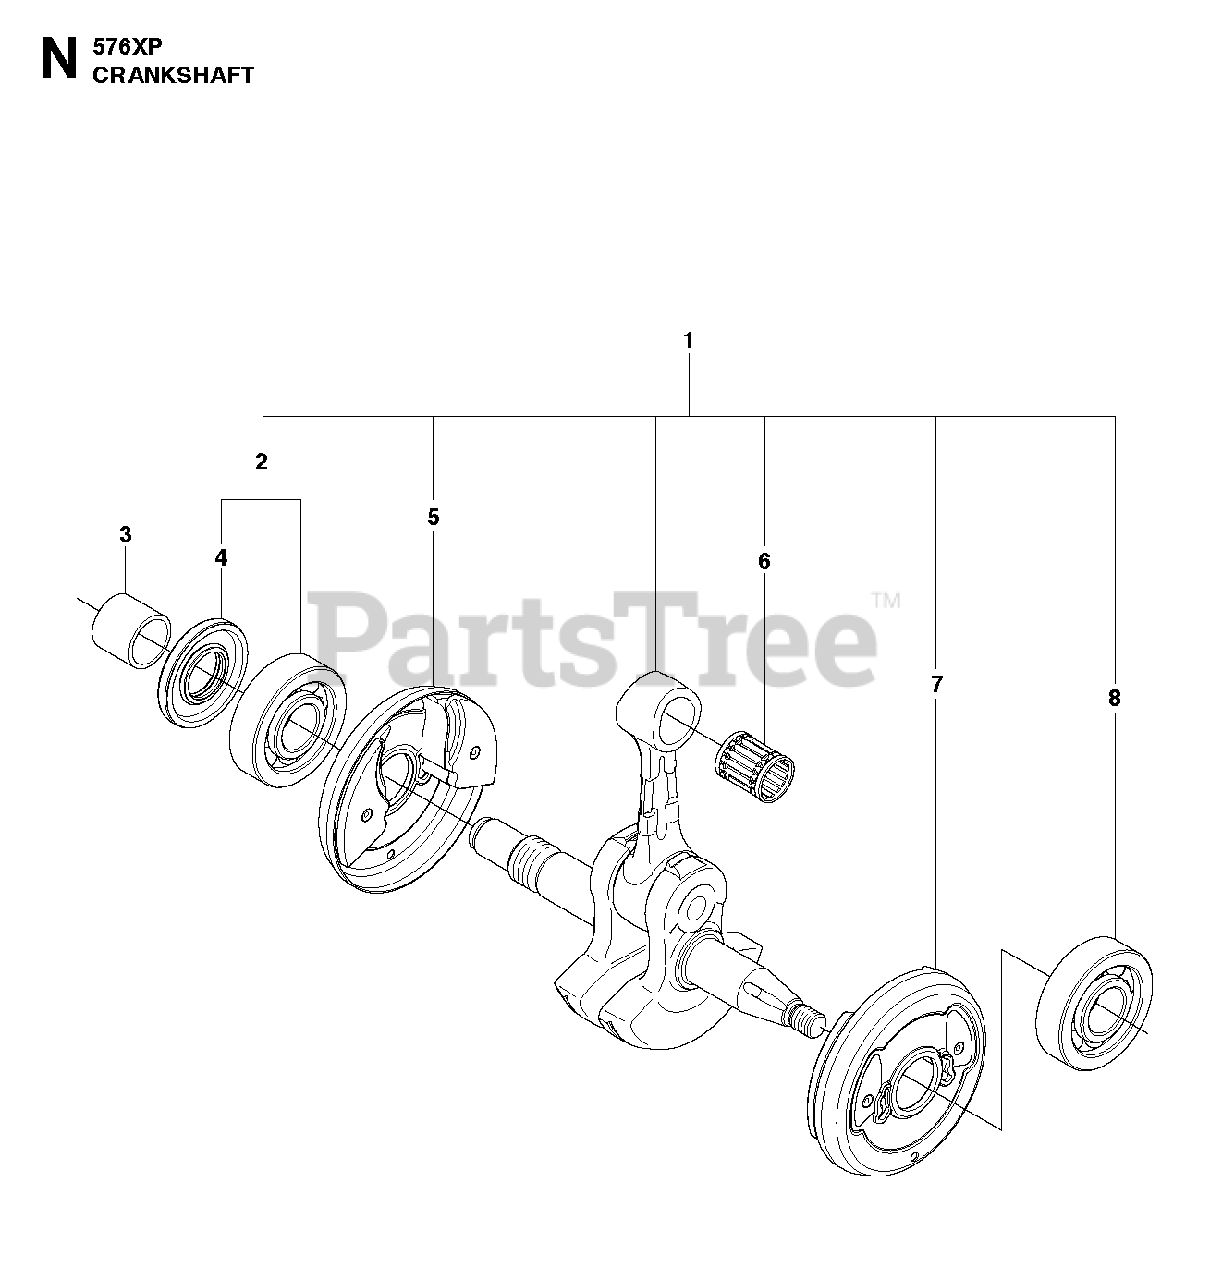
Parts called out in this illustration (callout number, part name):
1	RP CRANKSHAFT ASSY
2	BALL BEARING
4	RADIAL SEAL
5	CUP
6	SUPPORT BUSHING
7	CUP
8	BALL BEARING
